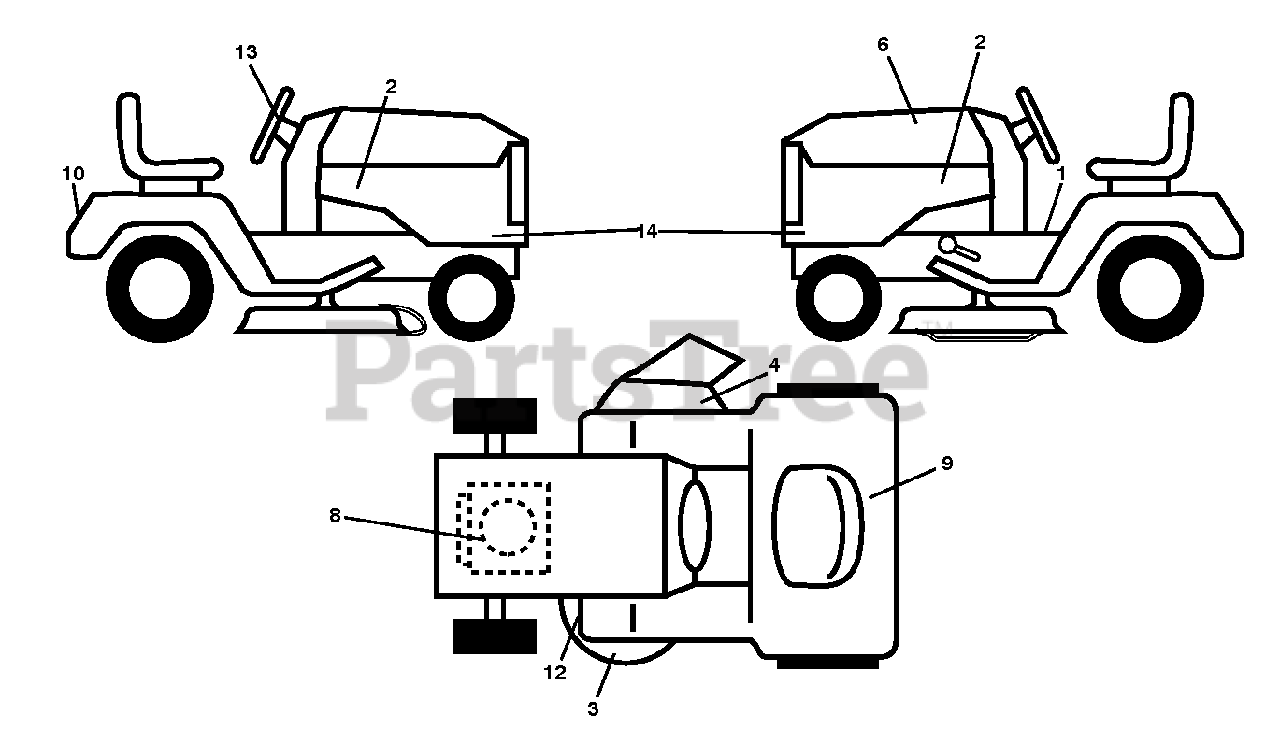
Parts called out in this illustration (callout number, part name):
1	DECAL.FENDER.WARNING.ENGLISH
2	DECAL.POULAN PRO.YEL/BLK.2017
3	DECAL.PPRO.10YRDECKWAR.POP
4	DECAL, DECK DEFLECTOR, WARNING
6	DECAL.RPL.BSM31.PB.46C.PMSTAL
8	Decal, Engine BS 17_5PB DOM 381669
9	DECAL BTRY SYMBOLS
10	Decal, REARFNDR Logo BLK 2017
12	DECAL.V-BELT.SCH.42/46"MEC/ELE
13	DECAL.STRWHL.STDSQ.PPRO.YEL.17
14	DECAL.SDPNL.PP175G46.BLK.PPRO
